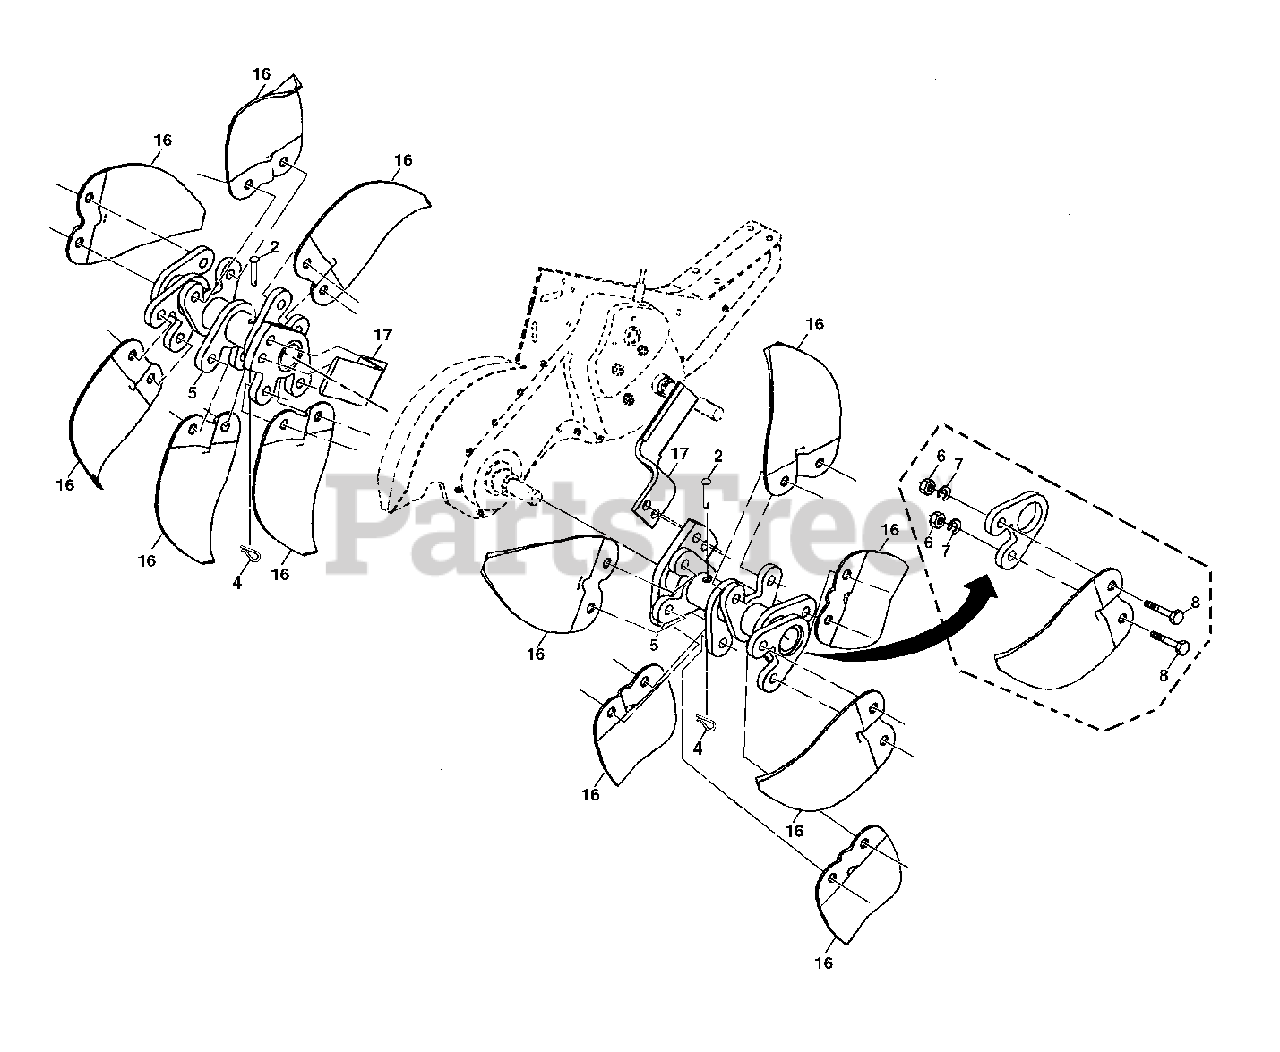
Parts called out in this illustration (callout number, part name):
2	CLEVIS PIN
4	SPRING RETAINER
5	HUB.ASM.DRT17.2004 (CMPL KIT)
6	NUT
7	WASHER, LOCK 3/8
8	BOLT.HEX.001X20.37-24X1.ZINC
16	TINE.SPADE
17	TINE.CLEANING BLACK
